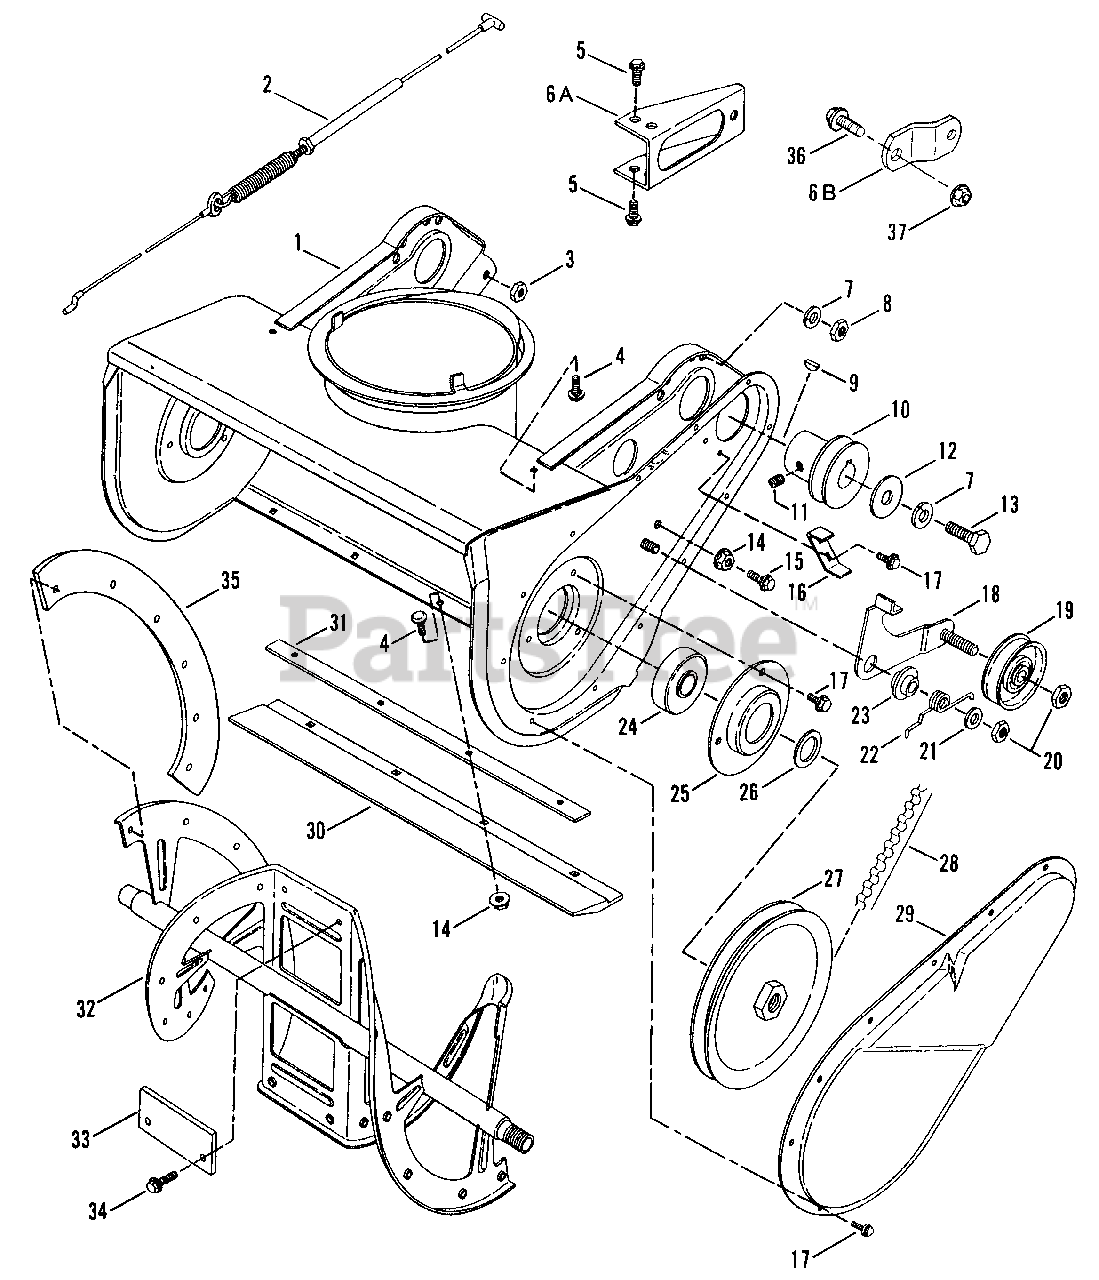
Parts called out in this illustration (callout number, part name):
1	ASSEMBLY, Blower Housing
2	CABLE, Clutch
3	NUT, 1/4-20 Hex Center Lock
4	BOLT, #10-24 x 5/8" Flat Head Carriage
5	SCREW, 1/4-20 x 3/8" Hex Washer Self-Tap
6A	BRACE, Engine
6B	BRACE, Engine
7	WASHER, 5/16 Split Lock
8	NUT, 5/16-18 Hex, Grade 8 or 5
9	KEY, (#6) 5/32 x 5/8" Woodruff
10	PULLEY, Engine
11	SETSCREW, 1/4-20 x 5/16"
12	WASHER, Flat (.343 I.D. x 1" O.D.)
13	SCREW, 5/16-24 x 3/4" Hex Head Cap
14	NUT, #10-24 Hex Flange Lock
15	SCREW, #10-24 x 5/8" Hex Washer Self-Tap, Grade 5
16	GUIDE, Belt
17	SCREW, #10-32 x 1/4" Slotted Hex Washer Head, Self-Tapping
18	ASSEMBLY, Idler Arm
19	PULLEY, Idler Arm
20	NUT, 5/16-18 hex Center-Lock
21	WASHER, 5/16 Flat
22	SPRING, Idler Brake
23	SPACER, Bearing
24	BEARING, Auger
25	RETAINER, Bearing
26	WASHER, 3/4" Flat
27	PULLEY
28	BELT, Auger 32.89
29	COVER, Belt
30	SCRAPER, Blade
31	BLADE, Wear Indicator
32	AUGER
33	SHOE, Flite Center 3.5" x 1.56"
34	SCREW, #10-24 x 5/6" Self-Tapping
35	SHOE, Flite
36	BOLT, 1/4-20 x 1/2" Hex Flange Lock, Grade 5
37	NUT, 1/4-20 Hex Flange Top Lock
